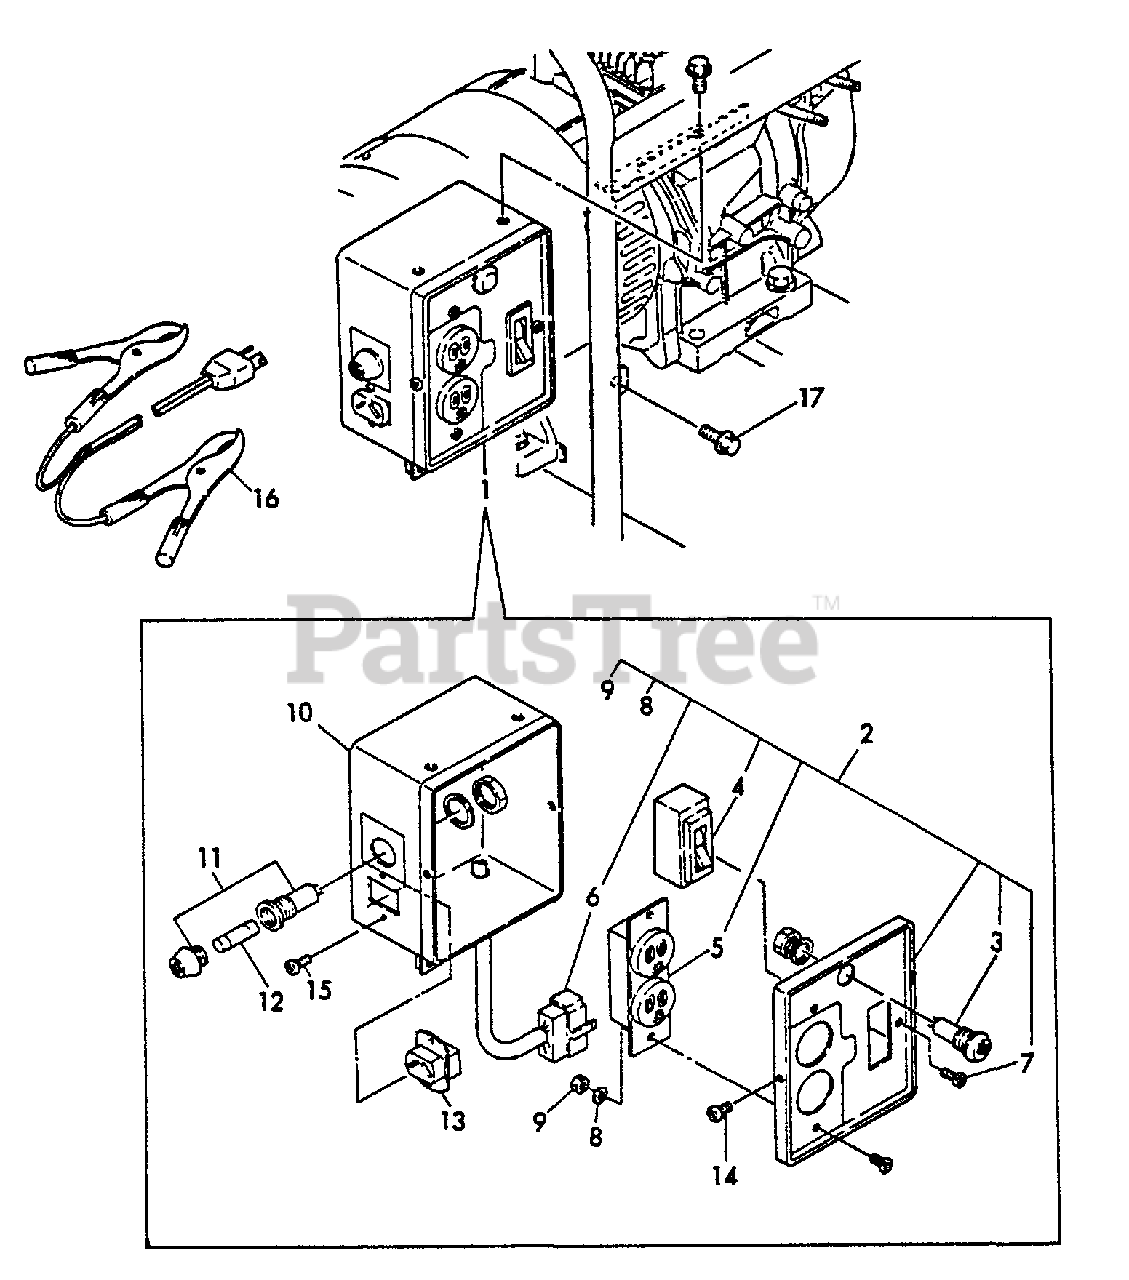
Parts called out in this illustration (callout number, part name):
1	PANEL BOX ASSY
2	PANEL ASSY
3	LAMP, PILOT - 100V
4	BREAKER - 17A
5	AC CONNECT
6	WIRE HARNESS
7	SCREW - 4×8
8	WASHER - 4
9	NUT - 4
10	BOX, PANEL
11	HOLDER, FUSE
12	FUSE - 15A
13	PLUG SOCKET 15A
14	SCREW - 4×8
15	SCREW - 3×10
17	BOLT - 6×8 -- PLATED
